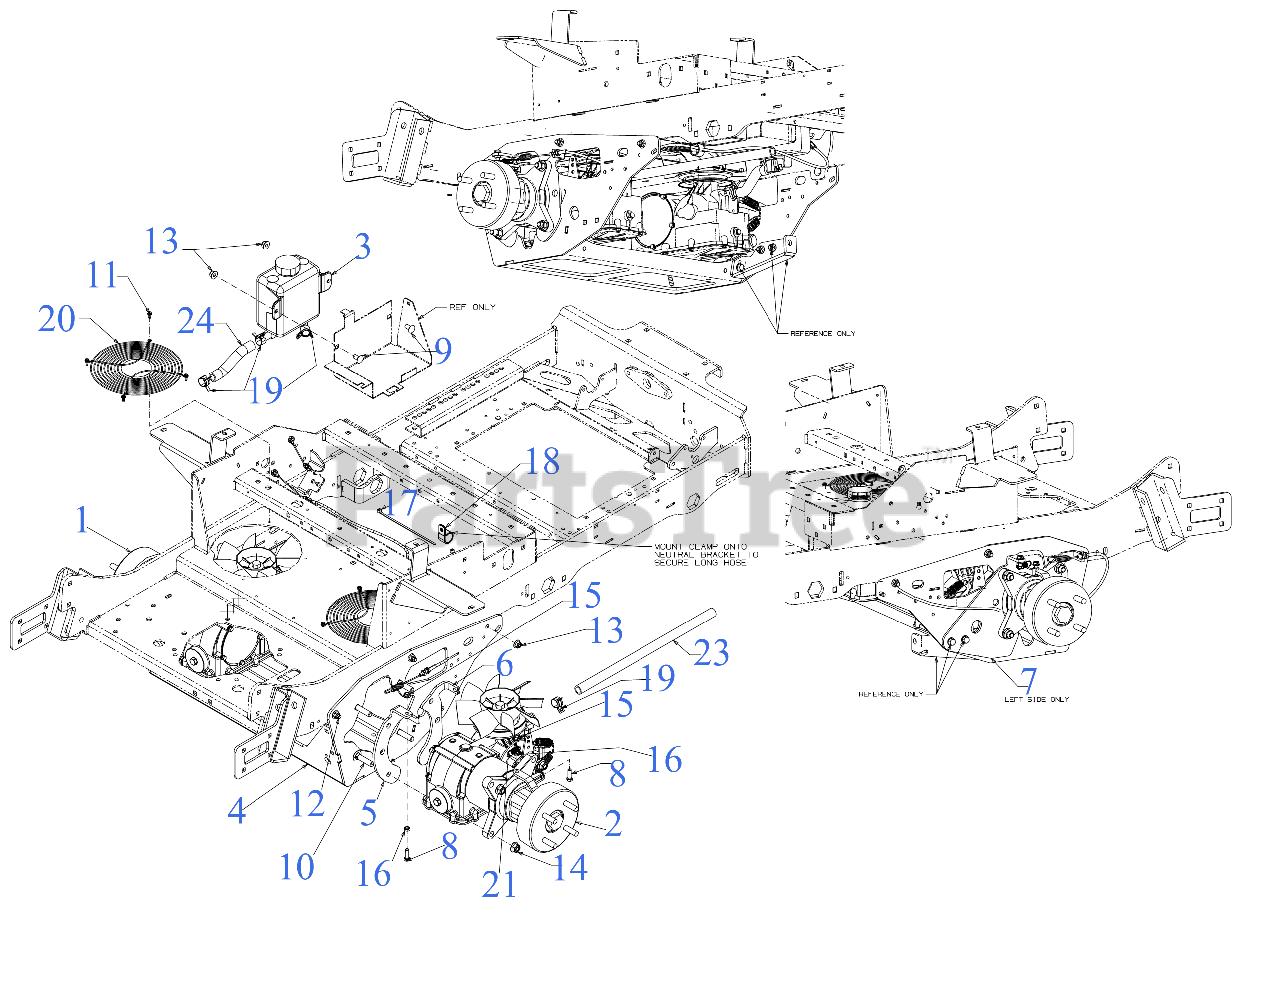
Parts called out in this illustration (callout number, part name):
1	TRANSMISSION (LH)
2	TRANSMISSION (RH)
3	HYDRO TANK ASSEMBLY
4	TRANSMISSION MOUNTING BRACKET
7	BRAKE SPRING MOUNTING BRACKET (LH)
8	SCREW 5/16-18 x 1.0 GR5
9	CARRIAGE BOLT 3/8-16 x .750 GR5
10	CARRIAGE BOLT 1/2-13 GR5
11	SCREW 10-24 x 0.500
12	CARRIAGE BOLT 3/8-16 X1.25 GR5
15	HEX FLANGE NUT
17	7" CABLE TIE
18	HOSE CLAMP 1.0"
19	HOSE CLAMP
21	EXTENSION SPRING .500 OD x 1.71
23	OIL HOSE 5/8 ID x 18.00 LG
